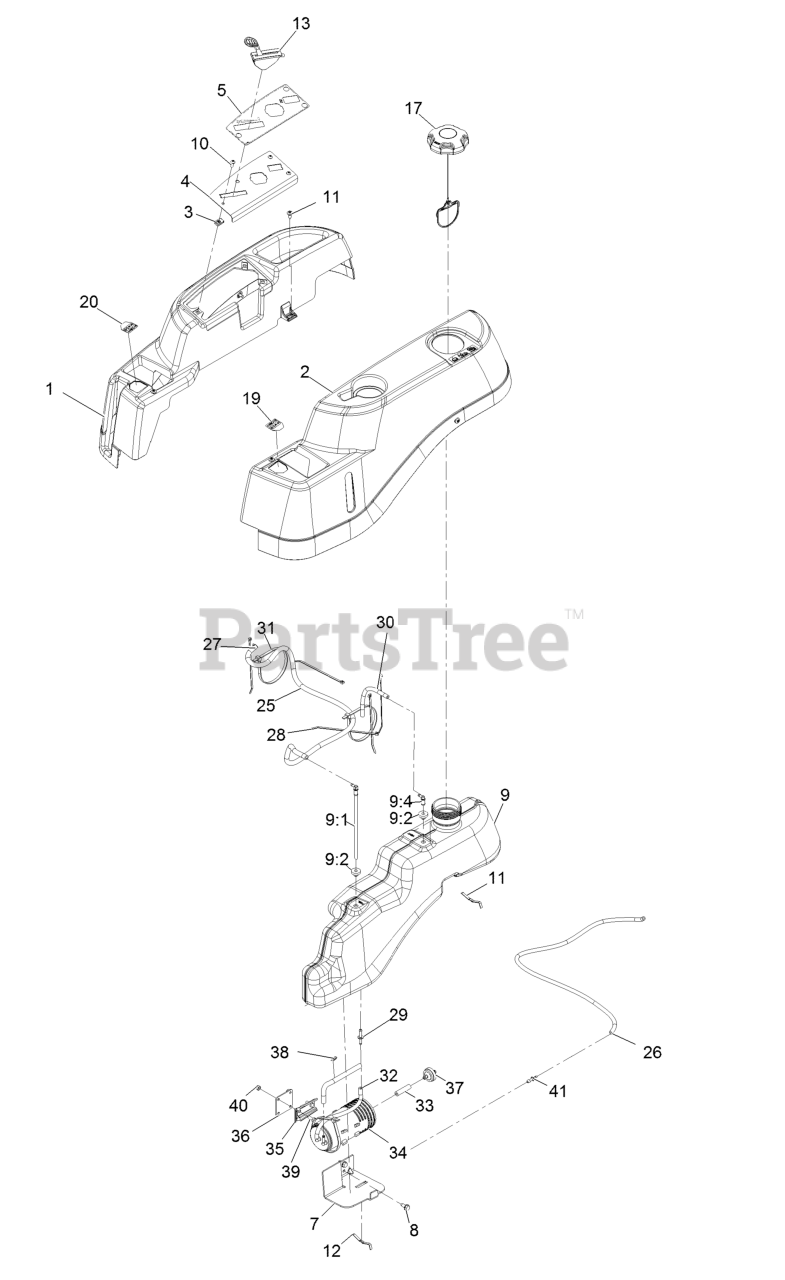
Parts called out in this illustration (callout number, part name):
4	PLATE-CONTROL
5	DECAL-PANEL, CONTROL
7	SUPPORT-TANK, FRONT
8	Screw-HWH 5/16-18 X 3/4 Tf
9	FUEL TANK ASM
9:1	CONNECTOR-ELBOW, 90 DEG
9:2	BUSHING
9:4	FITTING-PLASTIC
10	SCREW-PRH
11	SCREW-SHOULDER
12	SPRING
13	CABLE-THROTTLE AND CHOKE
19	DECAL-CONTROL LEVER LH
20	DECAL-CONROL LEVER RH
25	HOSE-FUEL
26	HOSE-FUEL
27	CLAMP-HOSE
28	TIE-CABLE
29	ADAPTOR-ORIFICE
30	HOSE-FUEL
31	TIE-CABLE
33	HOSE-FUEL
34	CANISTER-CARBON, 800CC
35	BRACKET-CANISTER, CARBON
36	PLATE-ADAPTER
37	FILTER-FUEL, INLINE
38	CARTRIDGE-VALVE, CHECK
39	SCREW-HH
40	NUT-LOCK, NI
41	FITTING-STRAIGHT
